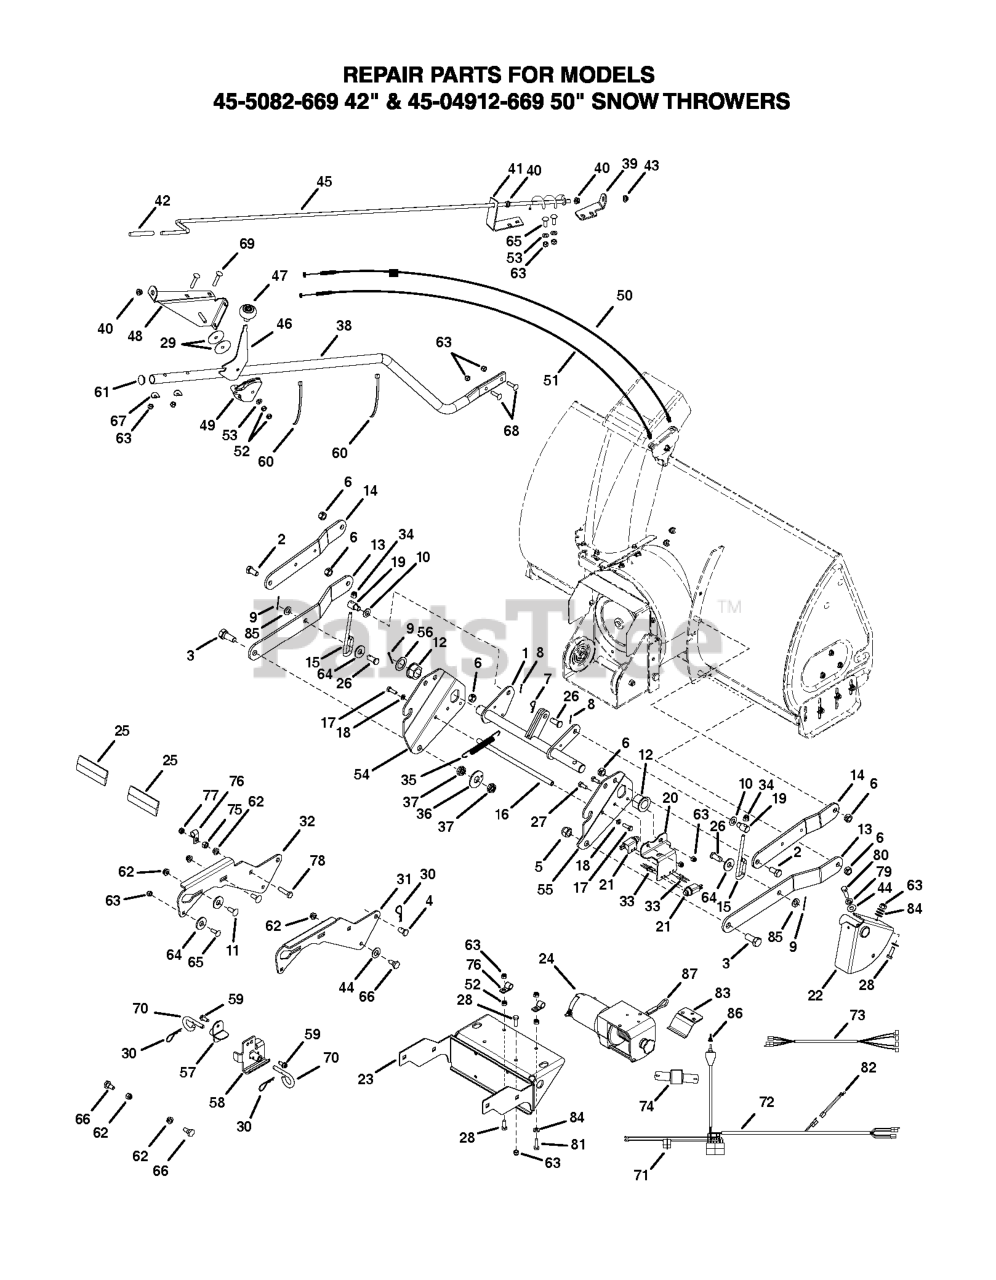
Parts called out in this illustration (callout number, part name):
6	NUT
7	PIN 47134
8	PIN 142
9	COTTER PIN
10	WASHER
11	BOLT 43350
16	ROD 24311
17	BOLT 47599
18	LOCK WASHER
25	REFLECTOR 47788
28	BOLT
31	PLATE 25678
32	PLATE 25679
34	NUT
39	BRACKET
43	NUT
52	NUT
53	WASHER
54	PLATE 24285
55	PLATE 24284
56	WASHER
57	BRACKET 65367
58	BRACKET 65450
59	BOLT
60	TIE WRAP 726-0178
62	NUT 47572
63	NUT 47810
64	WASHER R19172410
65	BOLT
66	BOLT 48106
67	WASHER
68	BOLT 43682
69	BOLT 44215
70	PIN 43038
75	NUT
79	LOCK WASHER
81	SCREW
84	WASHER R19111116
